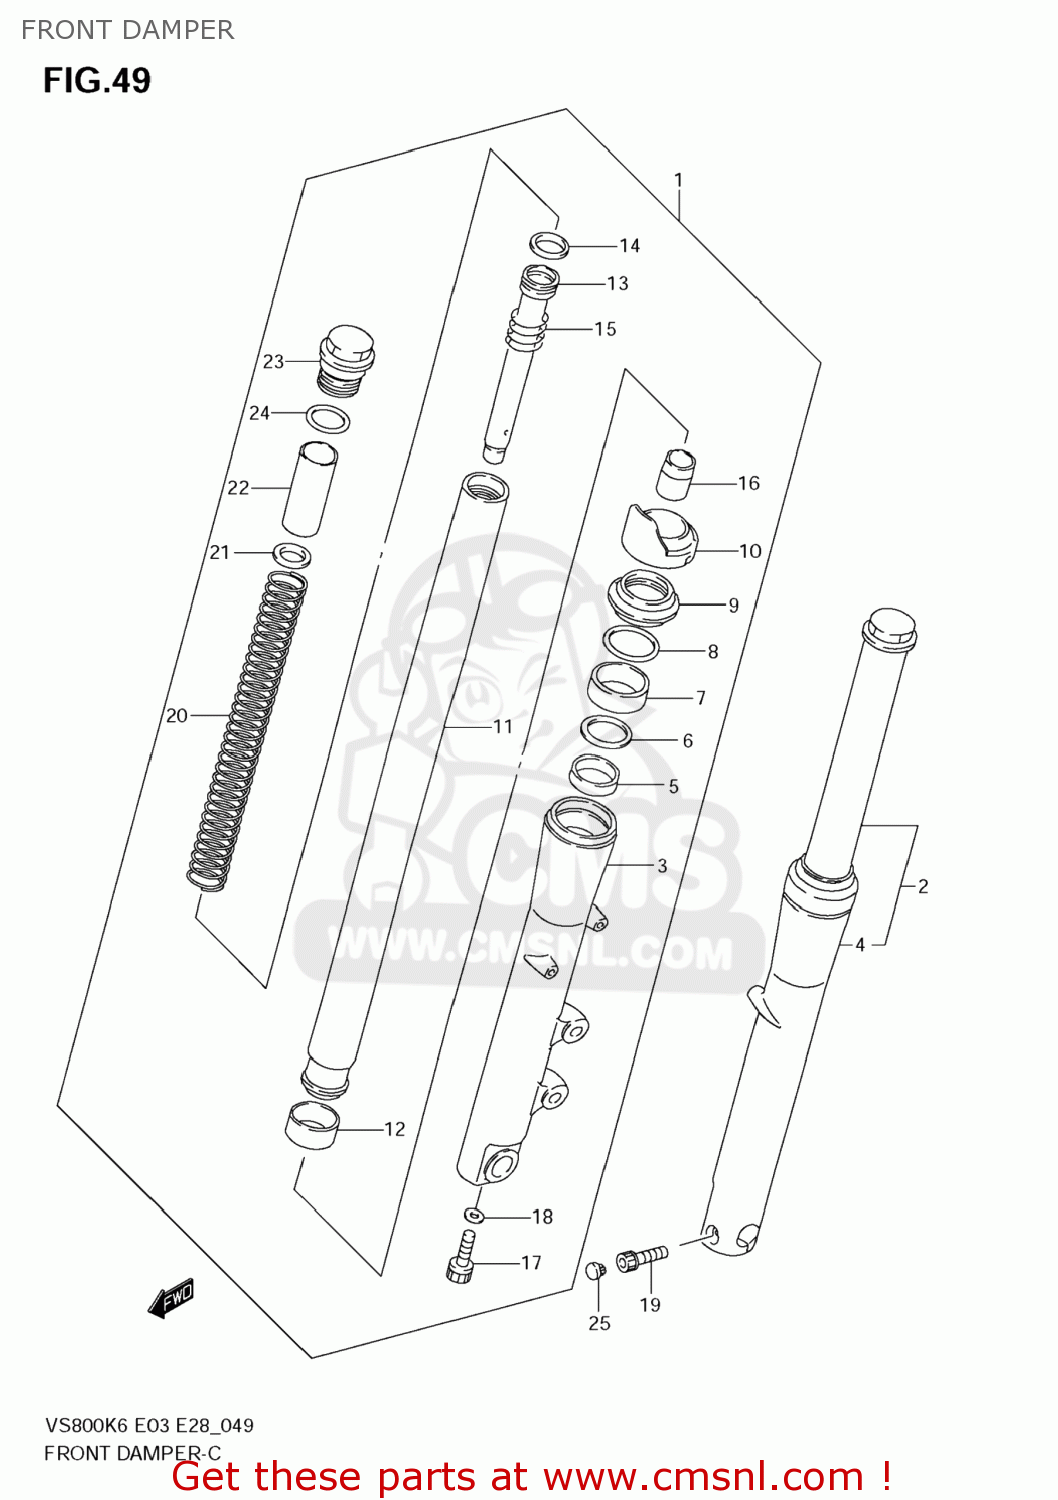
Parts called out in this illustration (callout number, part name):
1	DAMPER ASSY,FR FORK,R
2	DAMPER ASSY,FR FORK,L
3	TUBE,OUTER,R
4	TUBE,OUTER,L
5	BUSH,GUIDE
6	SPACER,SEAL
7	SEAL,OIL
8	RING,OIL SEAL STOPPER
9	SEAL,DUST
10	COVER,UPR,R
11	TUBE,INNER
12	BUSH,SLIDE
13	PIPE,SEAT
14	RING,PISTON
15	SPRING,REBOUND
16	PIECE,OIL LOCK
17	BOLT(8X27)
18	GASKET (NAS)
19	BOLT
20	SPRING
21	WASHER,SPRING
22	COLLAR,SPRING
23	BOLT,FORK
24	O RING
25	CAP(OD:14.5)
